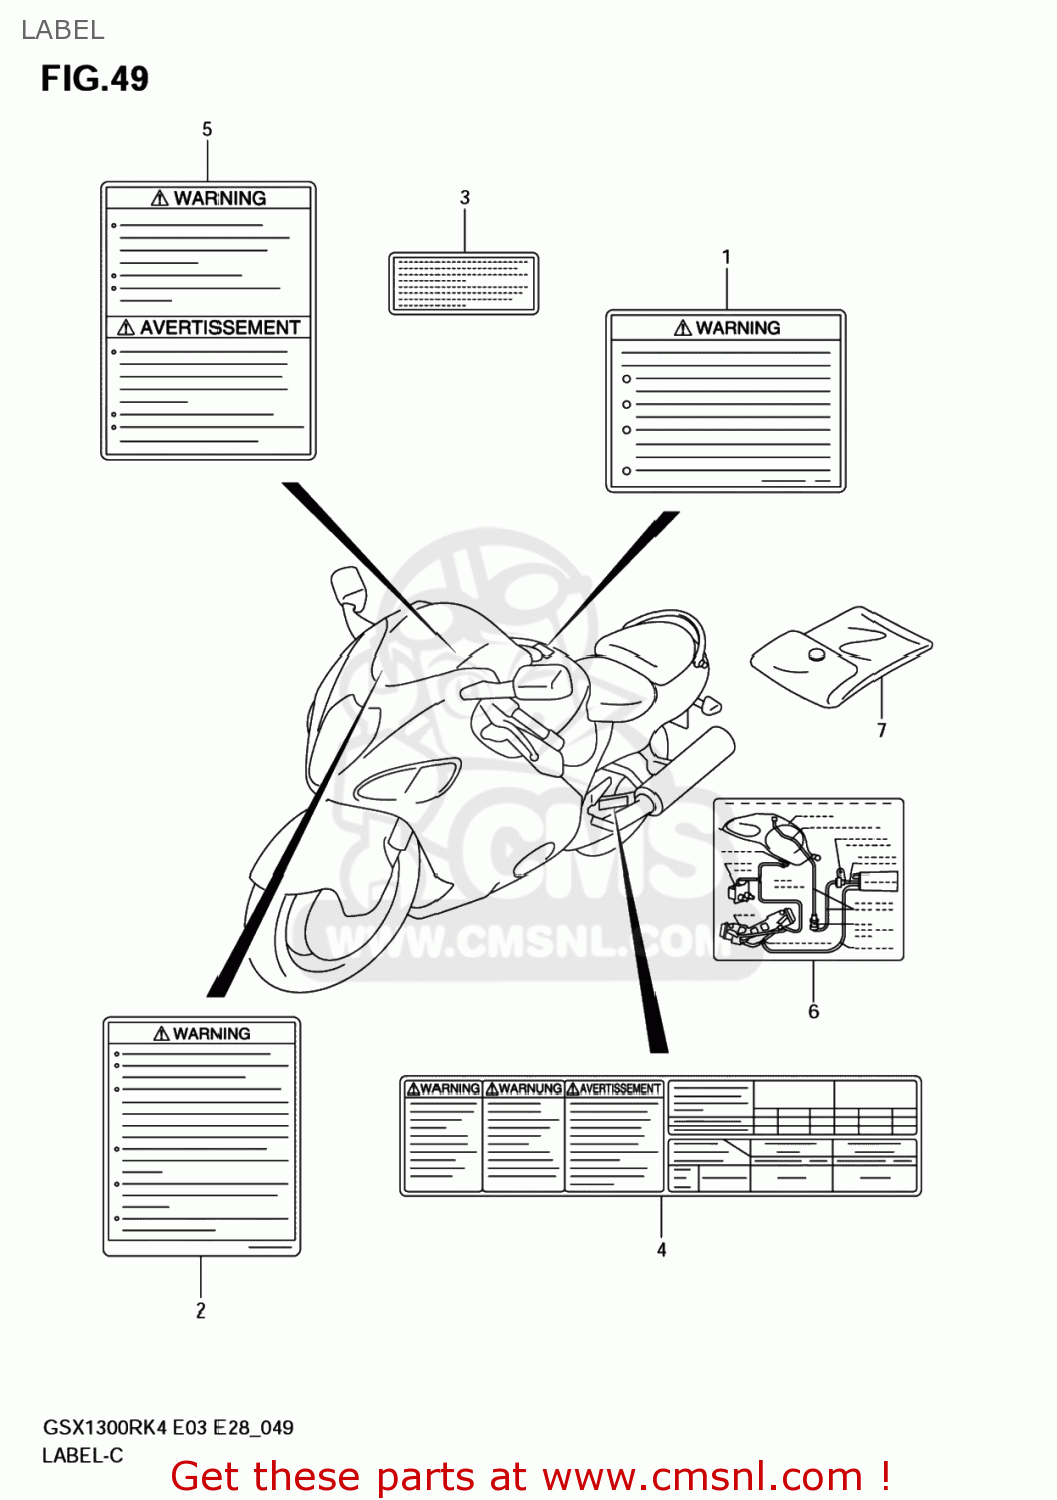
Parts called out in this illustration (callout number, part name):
1	LABEL,GENERAL WARNING
2	LABEL,SCREEN
3	LABEL,MANUAL NOTICE
4	LABEL,TIRE INFORMATION
5	LABEL,WARNING STEERING
6	LABEL,VACUUM HOSE ROUTING
7	BAG COMP,OWNERS MANUAL
8	MANUAL,OWNER'S
